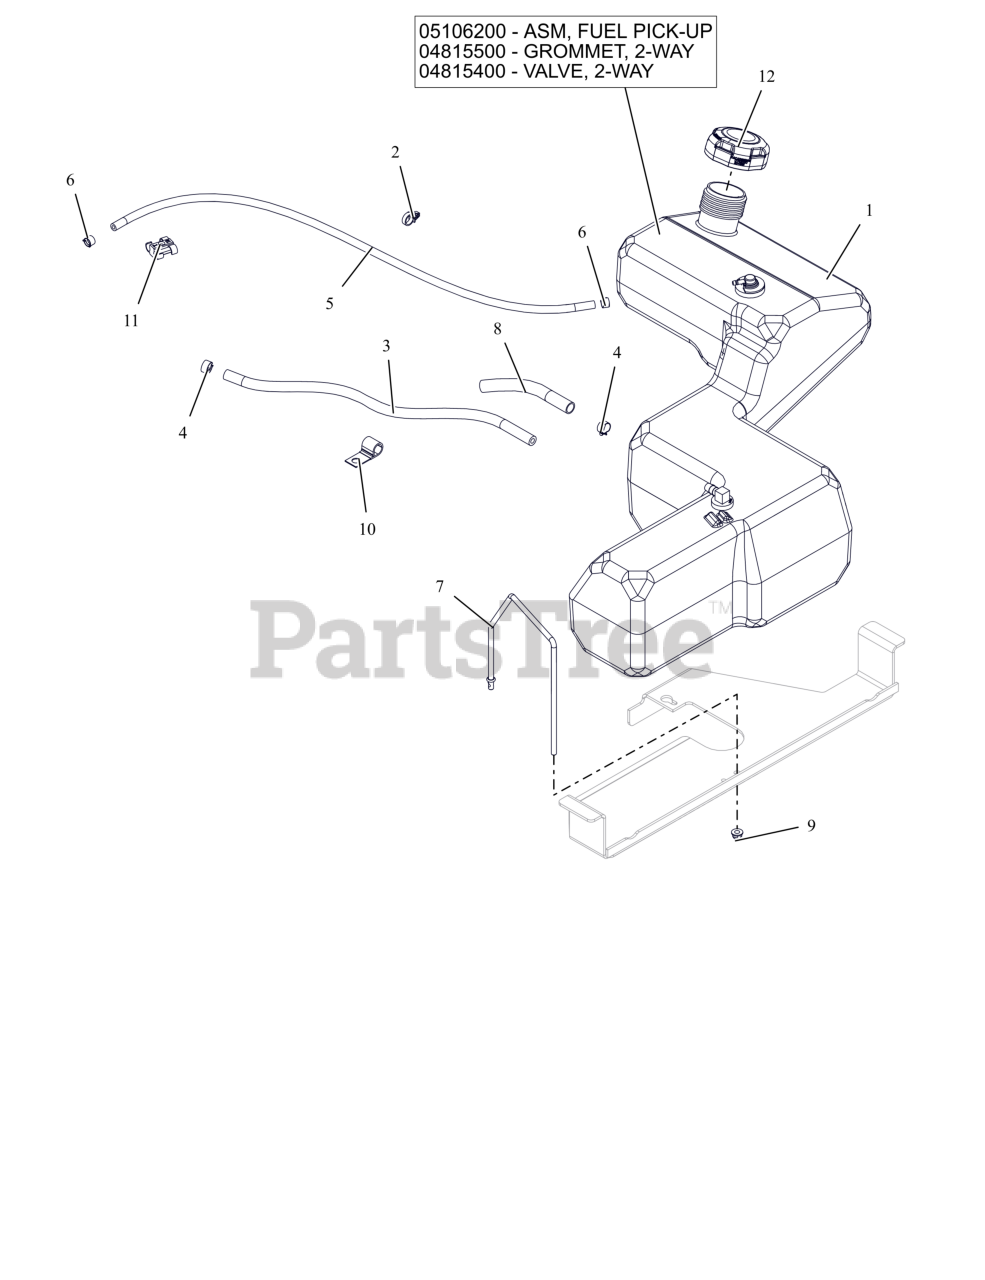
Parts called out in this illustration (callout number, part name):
1	ASM, FUEL TANK-IKON
1	ASM, IKON FUEL PICK-UP
1	GROMMET, 2-WAY
1	VALVE, 2-WAY
2	ROUTING CLIP (1/2" ID)
3	HOSE, .25 LOW-PERM BULK GAS
4	CLAMP, FUEL LINE
5	HOSE, .188 LOW-PERM BULK GAS
6	CLAMP-HOSE, SPRING .188
7	BRKT, FUEL TANK HOLD DOWN
8	WRAP, ANTIABRASION .5X.064WALL
9	NUT,NYL-FLG .25-20 GF ZCC
10	J-CLAMP
11	CLIP, T, .38-.50
12	CAP, FUEL - 2.25 RATCHET INLET VENT
